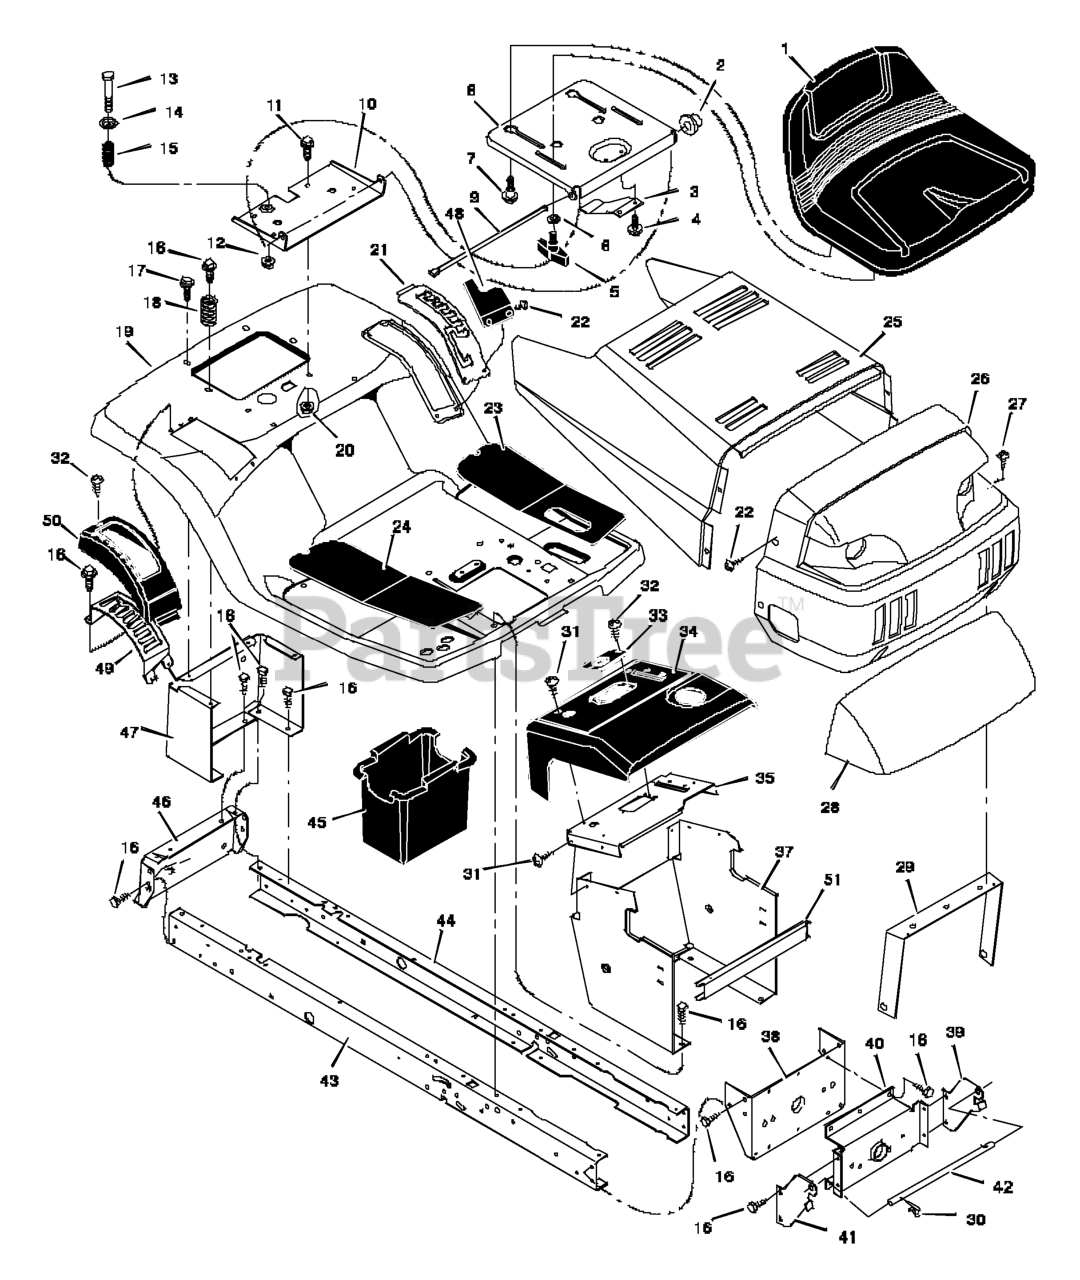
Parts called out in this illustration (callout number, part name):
2	Cap, Push On
5	Bolt, Wing
6	Washer
7	Bolt, Shoulder
8	Support, Seat
9	Rod, Pivot
10	Bracket, Pivot
11	Bolt
13	Bolt, Shoulder
15	Spring
19	Deck, Seat
20	Nut
21	Plate, Lift Index
23	Mat, Left
24	Mat, Right
26	Grille Assembly
29	Brace, Grille
30	Pin, Hair
31	Screw
33	Bearing, Steering
35	Plate, Dash
36	Panel, Access
37	Support, Dash
38	Bracket, Rear Hanger
39	Support, Left Grille
40	Axle, Hanger
41	Support, Right Grille
42	Rod, Pivot
43	Frame, Right
44	Frame, Left
45	Container, Battery
46	Plate, Hitch
47	Panel, Rear
48	Cover, Level Adjustment
49	Gate, Shift
50	Cover, Shift Gate
